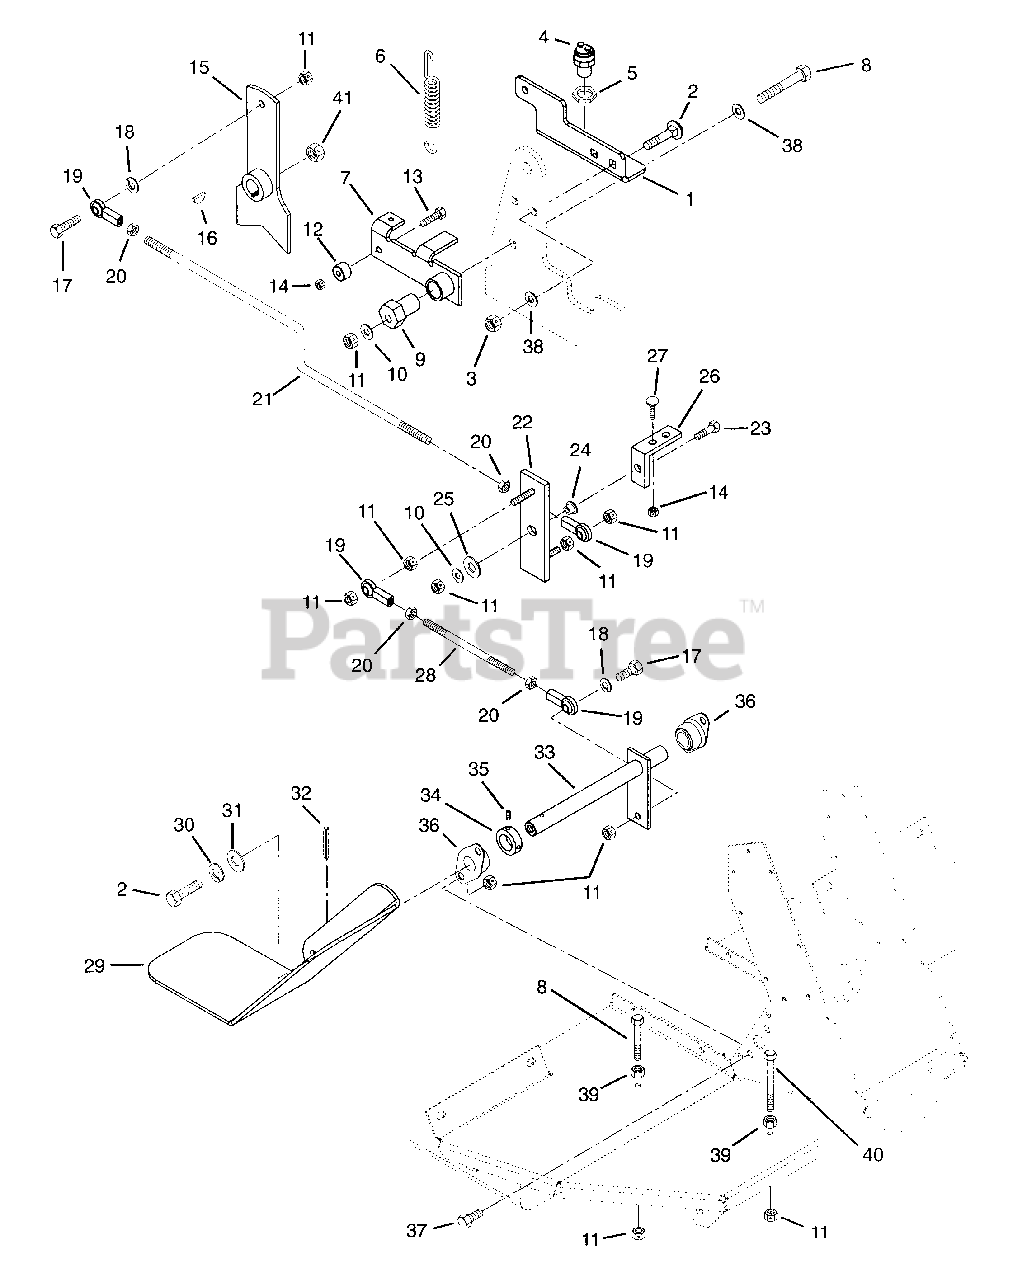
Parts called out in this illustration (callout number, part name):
2	Bolt-Round Head Square Neck .31-18 x .75
3	Nut-Locking-Center .31-18
4	Switch, Neutral
5	Nut-Stamped .56-18
6	Spring-Extension
7	Weldment, Detent Arm
8	Bolt-Hex .31-18 x 2.25
9	Eccentric
10	Washer-Flat-Steel .344 x .688 x .065
11	Nut-Locking-Center .31-18
12	Roller-Clutch Cam .250 x .750 x .5625
13	Bolt-Hex .25-20 x 1.00 Grade 5
14	Nut-Locking-Center .25-20
15	Weldment, Shift Arm
16	Key-Woodruff .125 x .625 x .250
17	Bolt-Hex .31-18 x 1.00 Grade 5
18	Washer-Locking .31 x .078
19	Rod End, 5/16 RH Female
20	Nut-Jam .31-24
21	Rod, Direction Control Rear
22	Weldment, Reverse Pivot Bracket
23	Bolt-Hex .31-18 x 1.25 Grade 5
24	Bushing-Flange .344 x .468 x .485 x .750
25	Washer-Flat-Steel .520 x .810 x .033
26	Bracket, Reverse Pivot Mount
27	Bolt-Round Head Square Neck .25-20 x .75 Grade 5
28	Rod, Direction Control Short
29	Weldment, Foot Control Lever
30	Washer-Locking .38 x .094
31	Washer-Flat-Steel .438 x 1.00 x .083
32	Pin-Roll .188 x 1.25
33	Weldment, Control
34	Bearing-Flange Locking Collar .75 x 1.85
35	Screw-Set .25-20 x .38 Socket Head
36	Bearing-Flange .751 x 2 Holes x .81
37	Bolt-Hex .31-18 x .75 Grade 5
38	Washer-Flat-Steel .328 x 1.0 x .094
39	Nut-Hex .31-18
40	Bolt-Hex .31-18 x 3.50 Grade 5
41	Nut-Locking-Center .50-13
